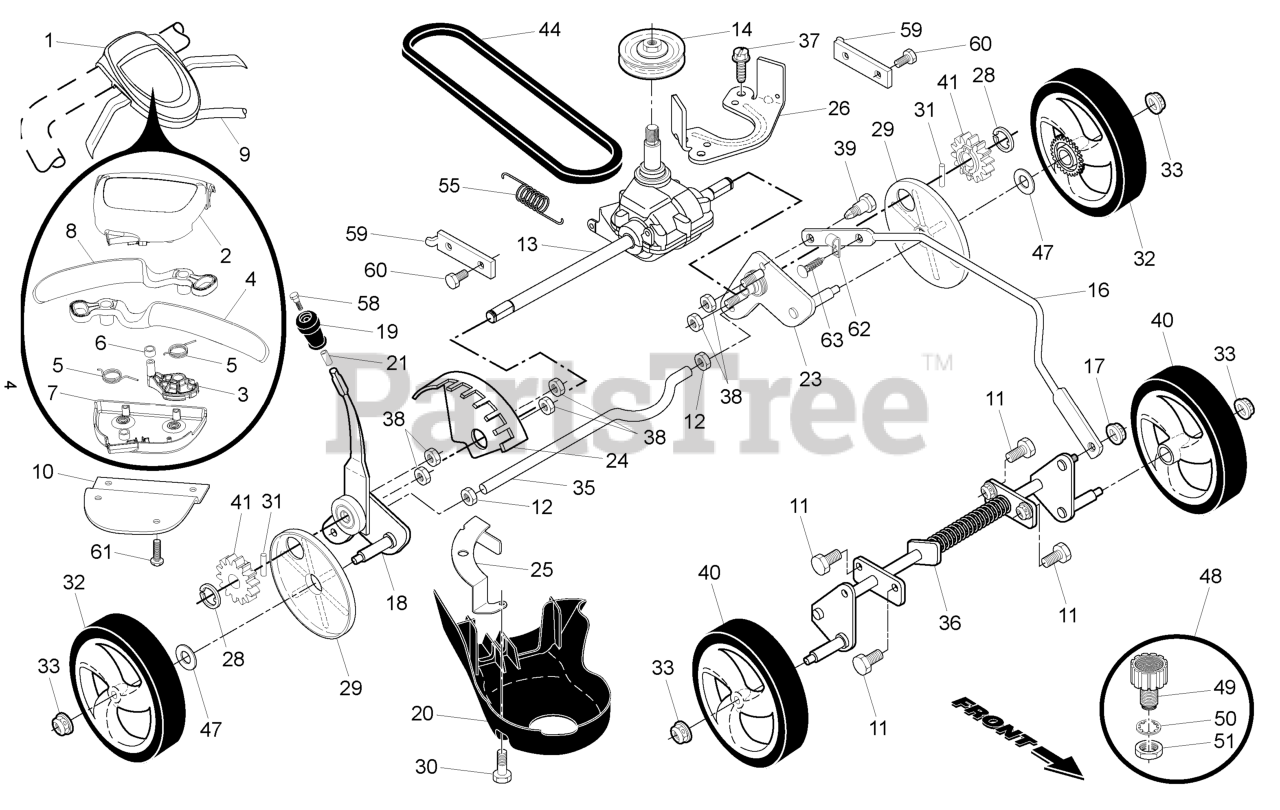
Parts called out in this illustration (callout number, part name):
1	RB CTRL.AW2.22+RGD.BS.GRY/BLK
2	RP CASE.CONT.ROL.TOP.HUSQV.
3	CAM.GEN2.DUAL.TRIGGER
4	LEVER.CONTROL.LH.22+.CURVE.BLA
5	SPRING, DRIVE CONTROL
6	BUSHING.CONTROL.CAM
7	COVER.DR.CONTROL.LOWER.GRAY
8	LEVER.CONTROL.RH.22+.CURV.BLAC
9	CABLE.CONTROL.22RGD.GEN2
10	BRACKET.DRIVE.CONTR.GEN2.BLACK
13	TRANMISSION.22+.RGD.AW
16	ROD.CONNECTING.RGD.22+.HW.BLAC
17	NUT.LOCK.5/16-18
18	Kit, Selector Assembly
19	KNOB.SEL.SPRING.22+.SP.RIB.BLK
20	COVER.BELT.22.RGD
21	SCREW.PLASTIC.ANCHOR.5/16
23	Wheel Axle Assembly, LH
24	BRACKET.WHL.ADJ.9.POS.W/PAD
25	BRACKET.DRIVE.COVER.RGD.BZP
26	BRACKET.TRANS.BELT.KEEPER.BZP
28	E-RING 7/16 RE
29	COVER.DUST.WHEEL
30	BOLT.HEX.HD.WASHER.5/16-18X.75
31	PAWL, DRIVE
32	WHEEL & TIRE ASSY, REAR
33	NUT.HEX.FLANGE.3/8-16.LO(3 2)
35	AXLE.REAR.RGD
36	AXLE.ASM.FRONT.RGD.BZP
38	NUT.HEX.FLANGE.1/4
39	SHOULDER BOLT SEMI GIMLET PT.
40	WHEEL & TIRES ASSY, FRONT
41	PINIION.14.TOOTH.RGD
44	BELT.DRIVE.RGD.PLUS
47	WASHER FLUT
48	KIT.WASH-OUT.PORT
49	FITTING, HOSE, WATER WASHOUT
50	WASHER.LOCK.INTERNAL.TOOTH
51	LOCKNUT.HEX.WITH.O-RING
58	SCREW.12-14X1.500
59	BRACKET.SUPPORT.22+.RWGD.BZP
60	BOLT.HEX.HD.WASHER.5/16-18X.75
61	SCREW, PHILLIPS HEAD 10 X 5/8
62	CLIP.CABLE.BLK
63	Fastener, Push
